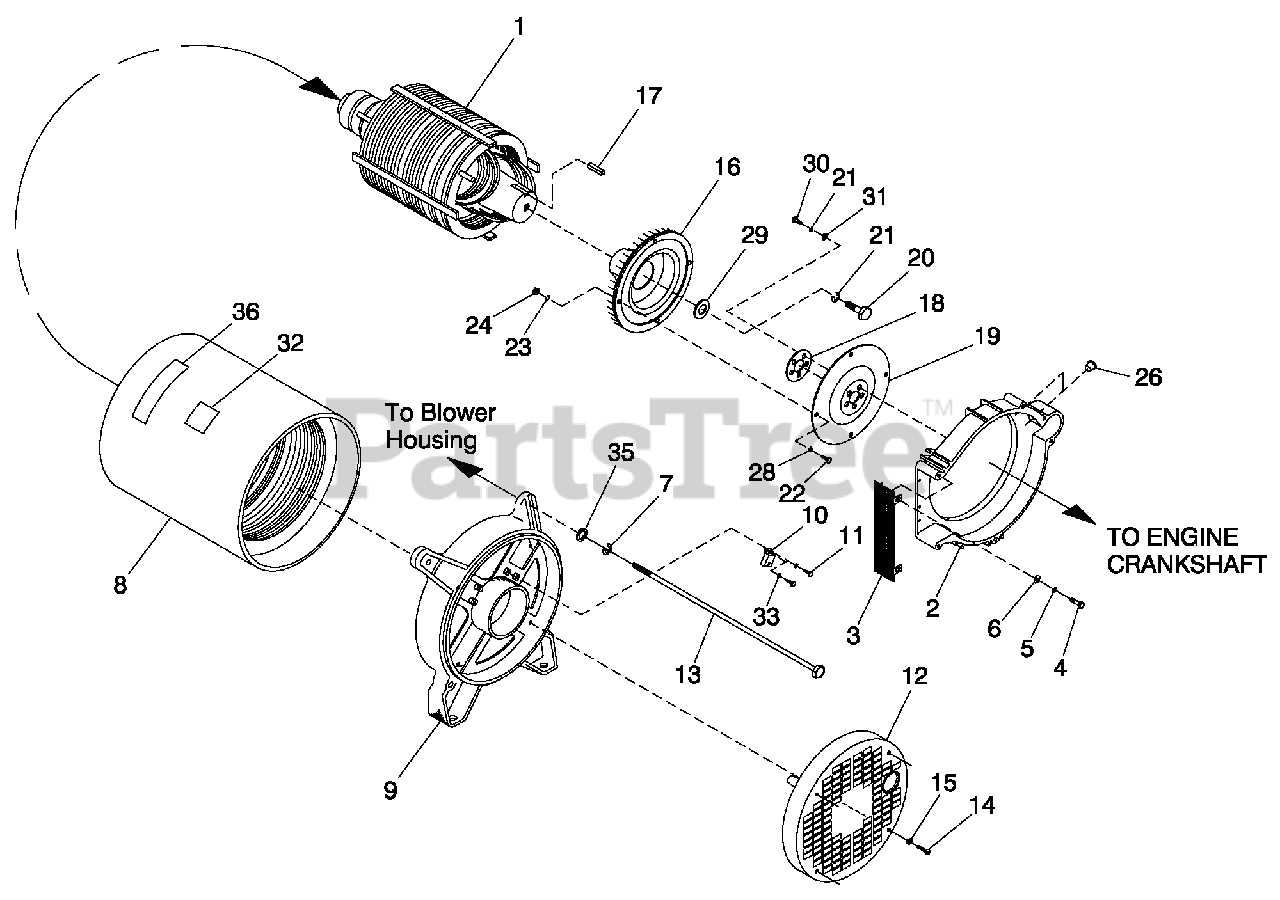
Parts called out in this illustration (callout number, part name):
1	ASSY ROTOR 20KW
2	HOUSING BLOWER
3	SCREEN AIR OUTLET
4	SCREW PPHM M5'0.8 X 8 ZINC
5	WASHER LOCK M5
6	WASHER FLAT M5
7	WASHER LOCK M8'5/16
8	ASSY STATOR 20KW 1PH A
9	BEARING CARRIER REAR
10	ASSY HOLDER BRUSH
11	SCREW PPHM M4'0.7 X 16
12	COVER REAR BEARING
13	BOLT STATOR X 16" LG
14	SCREW RHM #10'24 X 2
15	WASHER LOCK #10
16	FAN & RING GEAR ASSEM.
17	KEY SQ 3/8 X 1 STEEL
18	SPACER'FLEX PLATE
19	PLATE FLEX
20	SCREW HHC M12'1.75 X 35 G8.8
21	WASHER LOCK M12
22	SCREW HHC M10'1.5 X 35 G8.8
23	WASHER LOCK M10
24	NUT HEX M10'1.5 G8 YEL CHR
26	PLUG PLASTIC 3/8 NPT
28	WASHER FLAT 3/8'M10 ZINC
29	SPACER ROTOR SHAFT
30	SCREW HHC M12'1.25 X 25 G8.8
31	WASHER FLAT M12
32	DECAL WARN ENG START
33	WASHER SHAKEPROOF INT #8
35	WASHER FLAT .34 ID X .75 OD
36	DECAL DANGER STANBY UNITS
